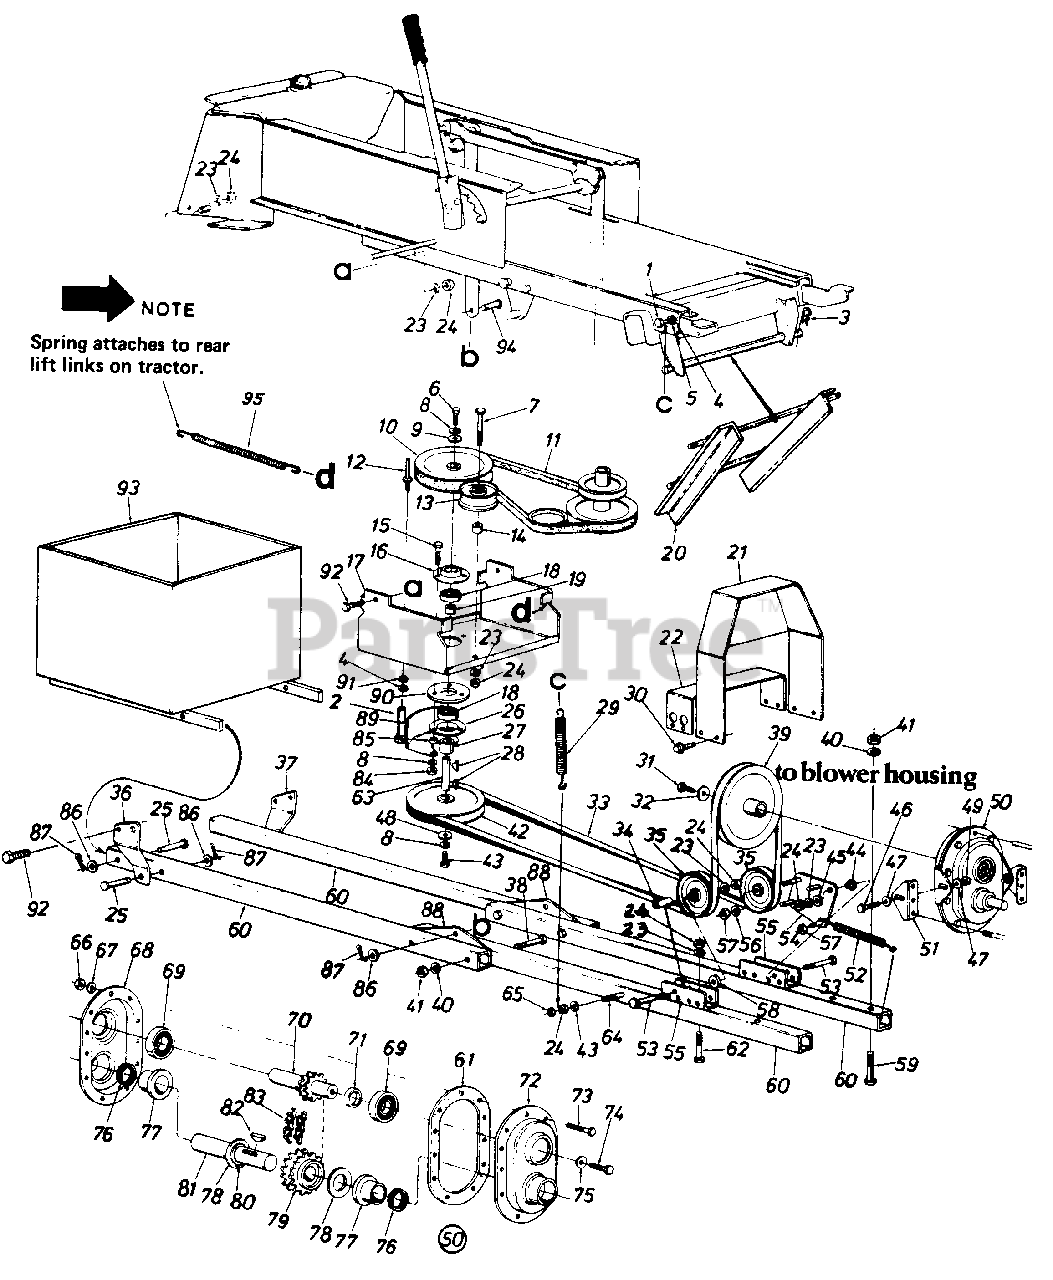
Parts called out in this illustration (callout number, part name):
1	Hex Bolt 1/4-28 x 1.50"
2	Clevis Pin Special 3/8" Dia. x 2.62" Lg.
3	Inter. Cotter Pin 1/2" Dia.
4	L.-Wash. 1/4" I.D.
5	Hex Nut 1/4-28 Thd.
6	Hex Bolt 3/8-24 x 1.0" Lg.
7	Hex Bolt 3/8-16 x 2.25" Lg.*
8	L.-Wash. 3/8" I.D.*
9	L.-Wash. .39" I.D. x 1.25" O.D.
10	5/8" "V"-Pulley .790" I.D. x 6.50 O. D
11	"V"-Belt 1/2" x 52.0" Lg.
12	Belt Guard Pin 1/4" Dia. x 1.68" Lg.
13	Fl.-Idler w/flanges 3.75" O.D.
14	Spacer.385" I.D. x .630" O.D. x.760" Lg.
15	Hex Bolt 5/16-24 x 1.50" Lg.
16	Open Brg. Housing 1.85" I.D.
19	Spacer 1.0" O.D. x .790" I.D. x.350" Lg.
20	Guide Bracket Ass'y.
21	Belt Cover Ass'y.
22	Belt Cover Brkt.
23	L.-Wash. 3/8" I.D.*
24	Hex Nut 3/8-16 Thd.*
25	Clevis Pin .50" Dia. x 2.75" Lg.
26	Bearing Housing 1.85" I.D.
27	Spacer .80" I.D. x 1.00" O.D. x.125" Lg.
28	Hi-Pro-Key 3/16 x 5/8"
29	Extension Spring 1.00" O.D. x 6.44" Lg.
30	Hex Wash. HD. Sf. Tap Scr. 5/124 x .50" Lg.
31	Hex L.-Bolt 3/24 x 1.00" Lg.
32	Bell.-Wash. .400"1.D. x 1.25" O.D.
33	"V"-Belt 1/2" Ax 112.0" Lg.
34	Spacer .39" I.D. x .62" O.D. x 1.74" Lg.
35	5/8" "V"-Belt Idler 4.00" O. D.
38	Hex Bolt 1/2-13 x 5.00" Lg.*
39	5/8" "V"-Pulley 1.00" I . D. x 7.50" O. D .
40	L.-Wash. 1/2" I.D.*
41	Hex Nut 1/2-13 Thd.*
42	5/8" "V"-Pullev .79"1.D. x6.5"
43	Hex Bolt 3/8-24 x 1.0" Lg.
44	ShoulderSpacer .625" I.D.
45	Fl.-Wash. .400" I.D. x 1.25" O.D.
46	Hex Bolt 5/1 6-1 8 x .75" Lg.*
47	Bell.-Wash. .345" I.D. x .88" O.D.
48	Fl.-Wash. .39" 1 .D. x 1.25" O.D.
49	Hex Nut 5/16-18 Thd.
50	Comp. Chain Gear Box Ass'y.
51	Gear Box Support Brkt.
52	Extension Spring .87" Dia. x 6.00" Lg.
53	Hex Bolt 3/8-16 x 3.0" Lg. (Grade 8)
56	Fl.-Wash. .385"1.D. x .87 O.D.
57	Hex Ins. L.-Nut 3/8-24 Thd.
58	Fl.-Wash. .400" I.D. x 1.25" O.D. x .157 Thk.
59	Hex Bolt 1/2-13 x 3.00" Lg.*
62	Hex Bolt 3/8-16 x 3.0" Lg. Grade 8)
63	Shaft - .787" Dia. x 3.81" Lg.
64	Hex Bolt 3/8-16 x 3.25" Lg.
65	Hex Cent. L.-Jam Nut 3/8-16 Thd.
66	Hex Nut 1/4-28 Thd.
67	Spr.-Wash. .270" I.D. x.57" O.D.
68	Gear Hsg. Half - L.H.
69	Ball Br. 1.00"1.D. x 2.00" O.D.
70	11-2x.5 Pitch-Sprkit. Shaft Ass'y.
71	Spacer 1.00" I.D. x 1.18" O.D. x .440 Lg.
72	Gear Hsg. Half - R . H.
73	Hex Bolt 1/4-28 x 1.00" Lg. (Grade 5)
74	Hex L.-Bolt 3/8-24 x 1.00" L.
75	Bell.-Wash. .400" I.D. x 1.25' O.D.
76	Oil Seal 1.25" x 1.75" O.D.
77	Flange Brg. 1.252" I.D.
78	Fl.-Wash. 1.25" I.D. x 2.00" O.D
79	DBL Sprkt. 19-2 Teeth x .500" Pitch
80	Snap Ring for 1.25" Dia. Shaft
81	GearShaft 1.25" Dia. x 6.0" Lg.
82	#A Hi-Pro Key 1/4 x 7/8" Dia. I
83	40-2 Chain 1/2" Pitch x 25 Links
84	Hex Nut 5/16-24 Thd.
85	Spacer .380" I.D. x .625" O.D. x.227" Lg.
86	Fl.-Wash. .510" I.D. x 1.0" O.D.
87	Inter. Cot.-Pin 1/2" Dia.
91	Hex Nut 1/4-20 Thd.
92	Hex Bolt 3/8-16 x 1.0" Lg.-Gr. 5
95	Ext. Spring
7845203	Rear Hanger Brkt. - L.H.
